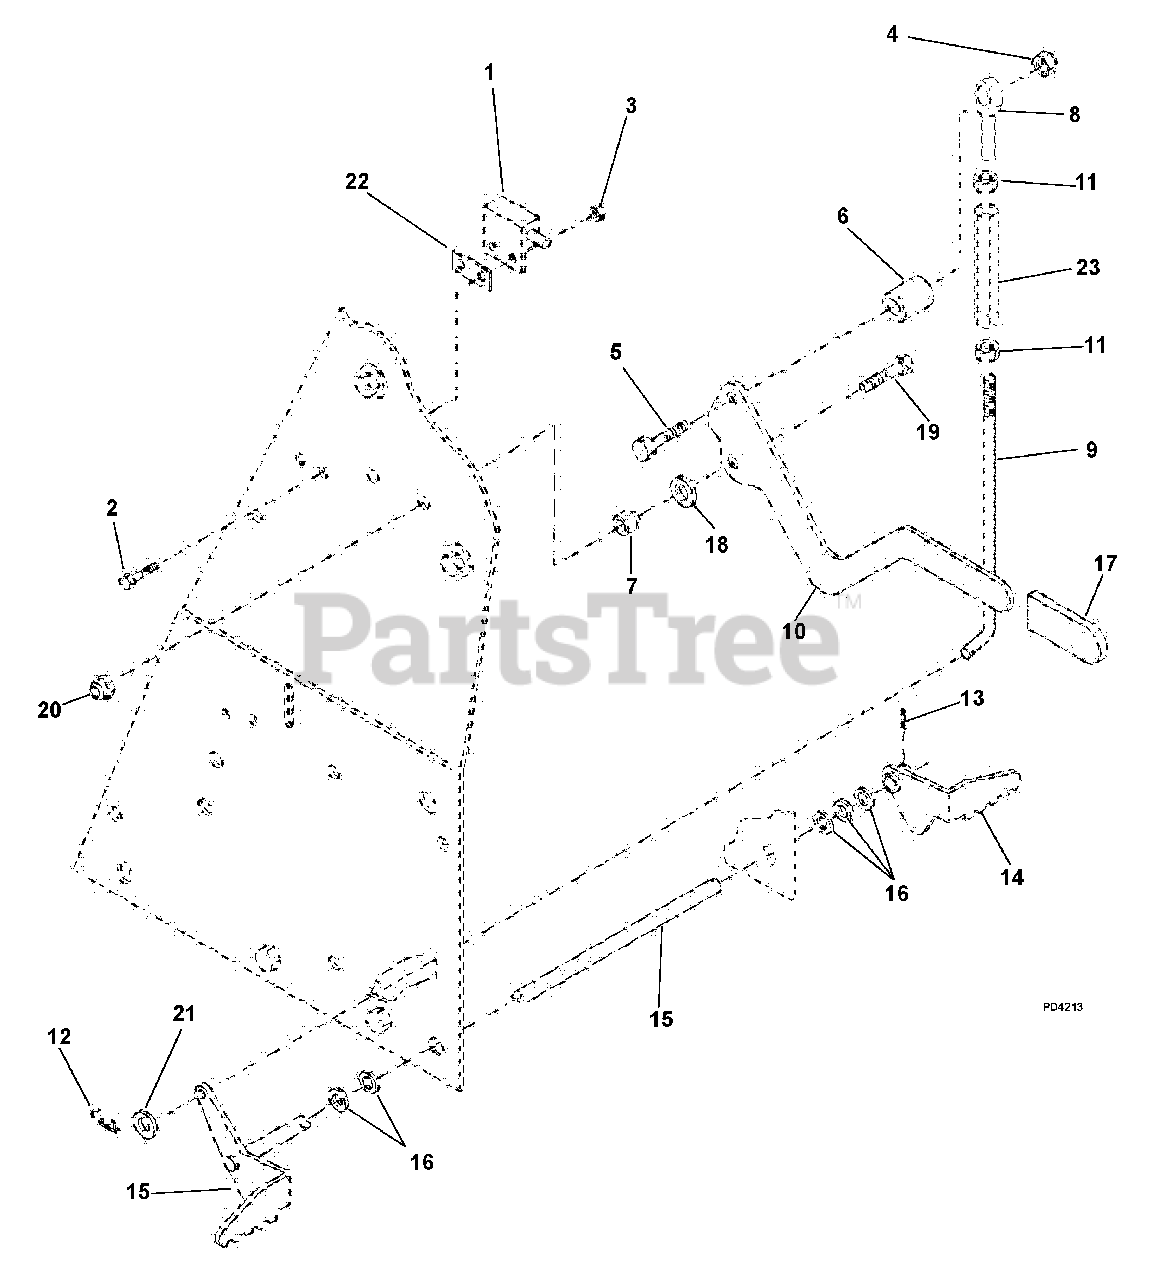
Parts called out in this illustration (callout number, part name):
1	Switch
2	Cap Screw, M5 x 0.8 x 20
3	Nut, Hex M5 x .8
4	Nut, Lock .38-16
5	Bolt, Hex .38-16 x 2.00
7	Bushing
8	End, LH Tie Rod
9	Rod
11	Nut, Hex .38-16
12	Pin HAR .094 x 1.53 5/16-1/2
13	Pin, Spring
15	Shaft
16	Washer, JD24 .89 x 1.375 x .048
17	Grip
18	Washer, 17/32" x 15/16" x 0.06
19	Bolt, M10 x 1.5 x 40
20	Nut, Lock, Nylon M10-1.5
21	Washer, Flat .406 x .812 x .065
22	Spacer Plate
23	Turn Buckle
